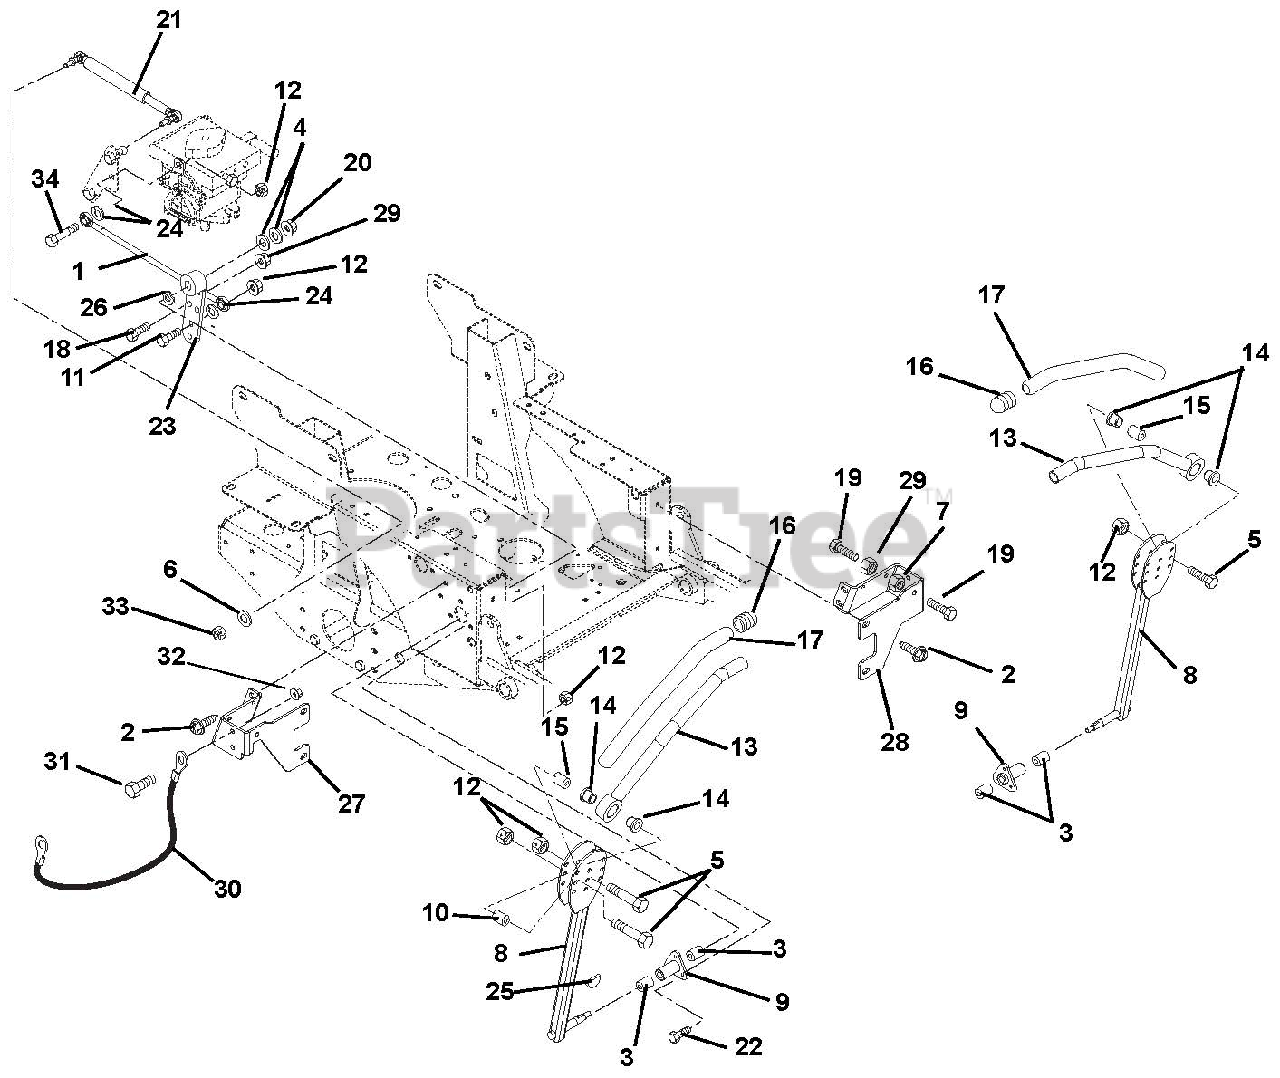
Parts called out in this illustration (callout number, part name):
1	Assembly, Steering Rod
2	Screw, Tapping .38-16 x .75 Hex Washer Head
3	Bushing .625 x .75 x .50
4	Washer, Flat Steel .406 x .812 x .065
5	Bolt, Hex .31-18 x 1.75 Grade 5
6	Washer, Flat Steel .38 x .875 x .083
7	Nut, Hex Jam .375-16
8	Control Arm
9	Housing, Bushing
10	Eccentric
11	Bolt, Hex .31-18 x 1.25 Grade 5
12	Nut, Nyloc Flange .38-18
13	Handle Weldment Left-Hand
13	Handle Weldment Right-Hand
14	Bushing, Flange Nylon .762 x 1.48 x .44
16	Caplug, Handlebar
17	Grip, Handlebar
18	Bolt, Hex .375-16 x 1.75
19	Bolt, Hex .38-16 x 1.25 Grade 5
20	Nut, Nyloc Flange .38-16
22	Bolt, Hex .31-18 x 1.00 Grade 5
23	Weldment, Pivot Arm
24	Washer, Locking .31 x .078 Regular
25	Key, Woodruff .13 x .63
26	Wave Washer
27	Stop, Steering-Right Hand
28	Stop, Steering-Left Hand
29	Nut, Locking Jam Center .375-16
30	Cable, Hood
31	Bolt-Hex .25-20 x .75 Grade 5
32	Nut, Nyloc Flange .25-20
33	Nut, Locking Nylon M8-1.25
34	Bolt, Hex .31-18 x 1.50 Grade 5
